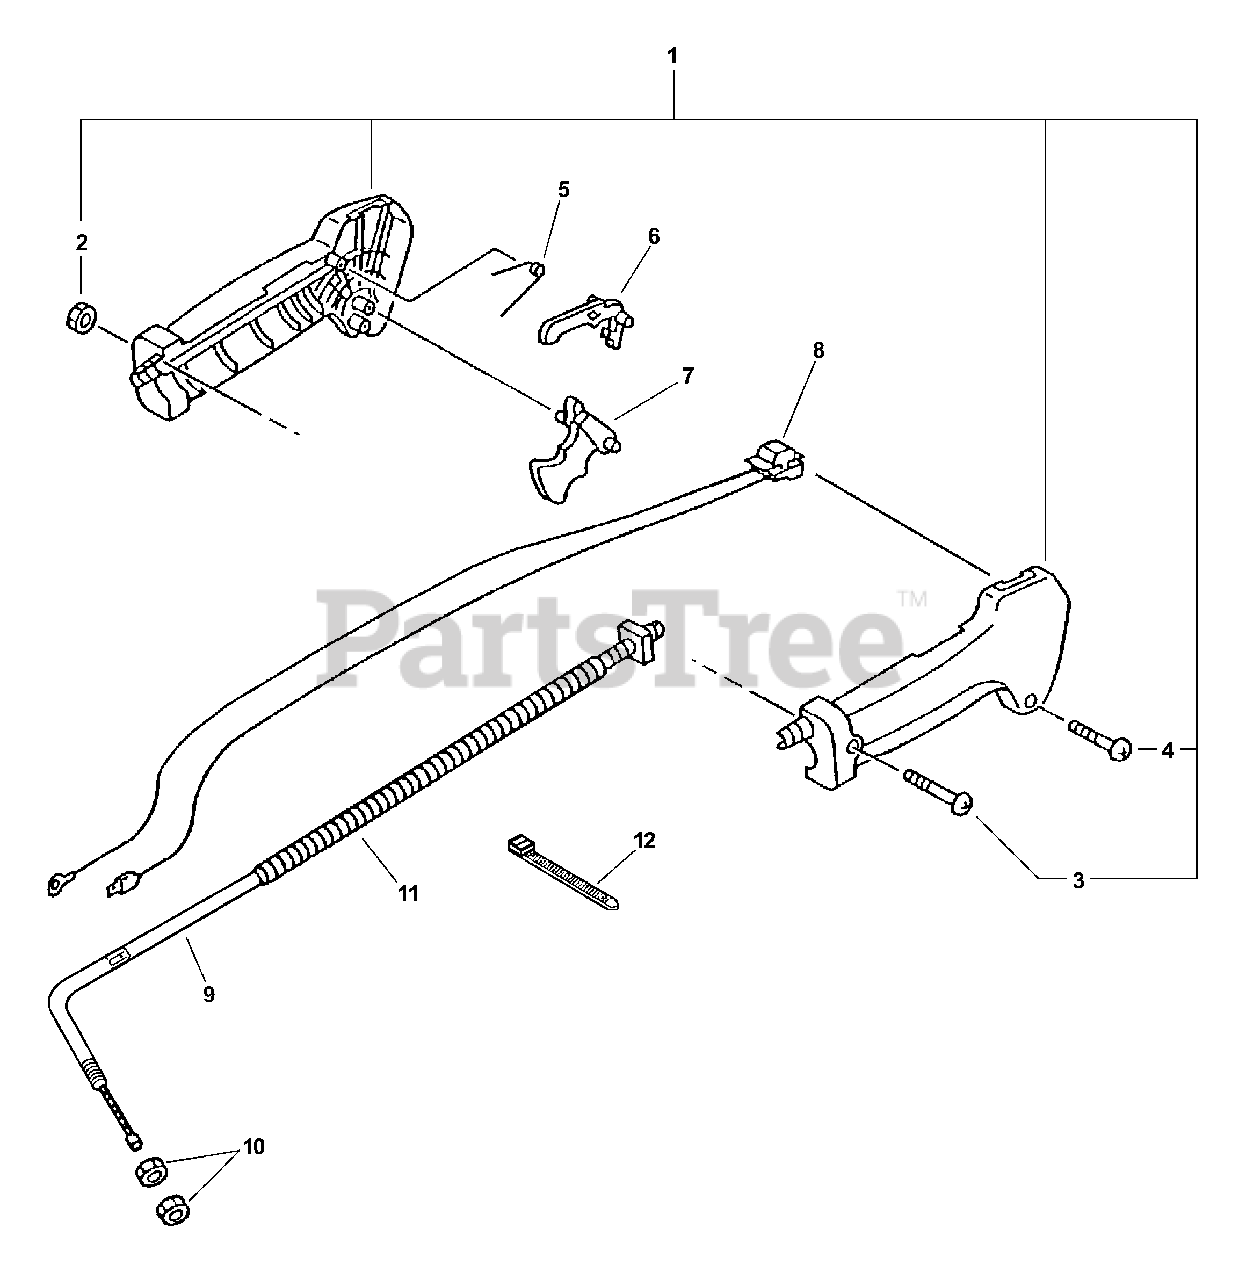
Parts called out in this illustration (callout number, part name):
1	THROTTLE CONTROL ASSY
3	SCREW - 5X30
4	SCREW - 3X25
5	SPRING, LOCKOUT LEVER
6	LOCKOUT, THROTTLE
7	TRIGGER, THROTTLE
8	SWITCH, IGNITION
9	CABLE, THROTTLE
11	TUBE, PROTECTIVE - CORRUGATED
12	TIE, CABLE
